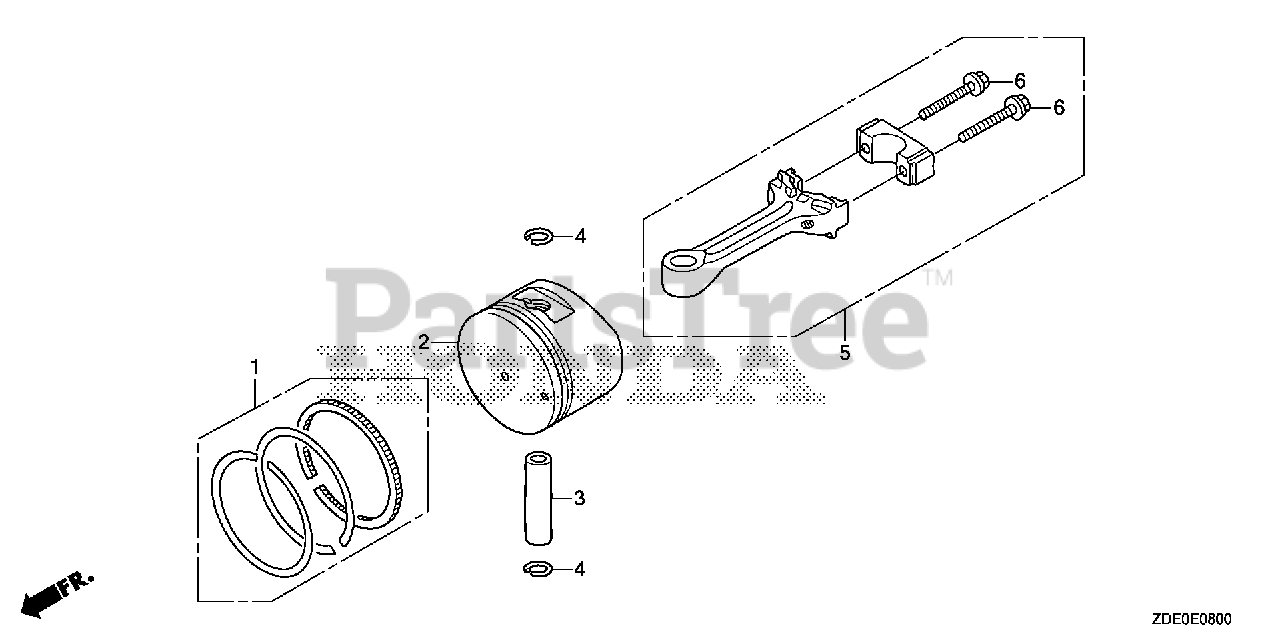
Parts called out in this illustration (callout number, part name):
1	RING SET, PISTON (STD)
2	PISTON (STD)
3	PIN, PISTON
4	CLIP, PISTON PIN (10MM)
5	ROD ASSY., CONNECTING
6	BOLT, CONNECTING ROD
